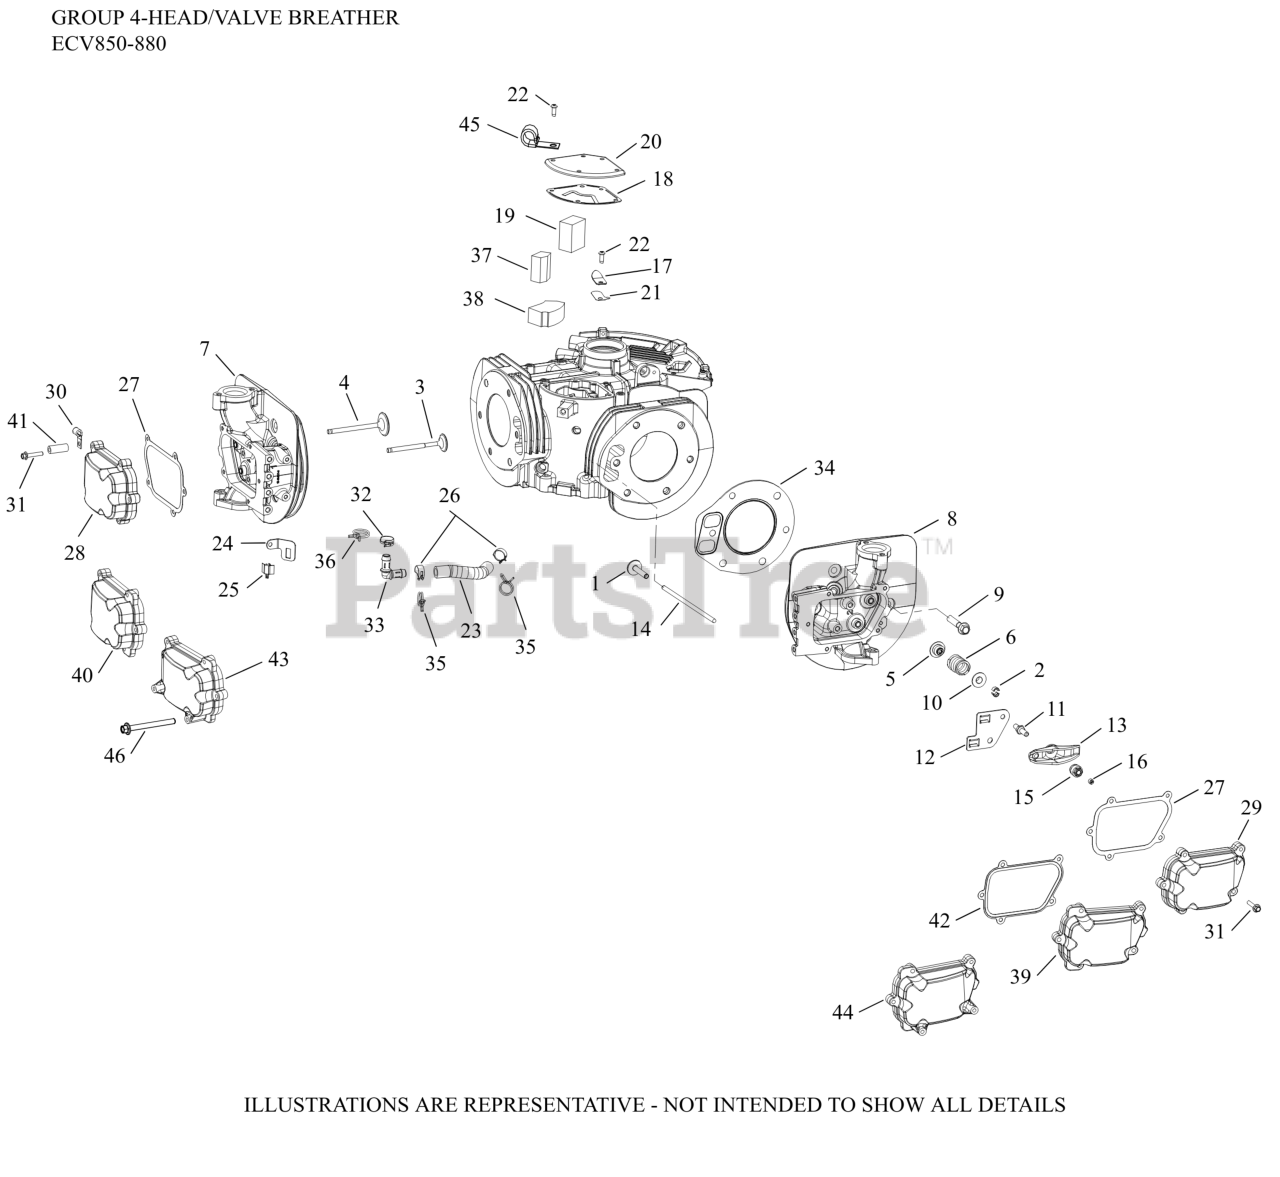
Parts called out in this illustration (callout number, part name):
1	TAPPET, COATED
2	KIT, RETAINER
3	VALVE, EXHAUST
4	VALVE, INTAKE
5	SEAL, VALVE STEM
6	SPRING, VALVE
7	CABEZA CILINDRO NO.1/KIT,CYLINDER HEAD#1
8	KIT,CYLINDER HEAD#2
9	SCREW, HEAD
10	CAP, VALVE SPRING
11	STUD, ROCKER
12	PLATE, PUSHROD GUIDE
13	ARM, ROCKER
14	ROD, PUSH
15	PIVOT, ROCKER ARM
16	SCREW, SET
17	RETAINER, REED
18	GASKET, BREATHER-(#1904118S)
20	COVER, BREATHER
21	REED, BREATHER
22	SCREW, BUTTON HEAD
23	HOSE, BREATHER
24	BRACKET, OXYGEN SENSOR
25	CLIP, O2 SENSOR
33	FITTING, 90 DEGREE
34	KIT, HEAD GASKET (824)
35	CLAMP, HOSE
36	CLAMP, HOSE
37	FILTER, BREATHER MEDIA (LOWER HALF)
38	FILTER, BREATHER MEDIA (UPPER HALF)
39	KIT, VALVE COVER #2
40	KIT, VALVE COVER #1
NI	GASKET, VALVE COVER
NI	CLIP, CABLE (KM)
NI	SCREW, FLG M6X1.0X80
